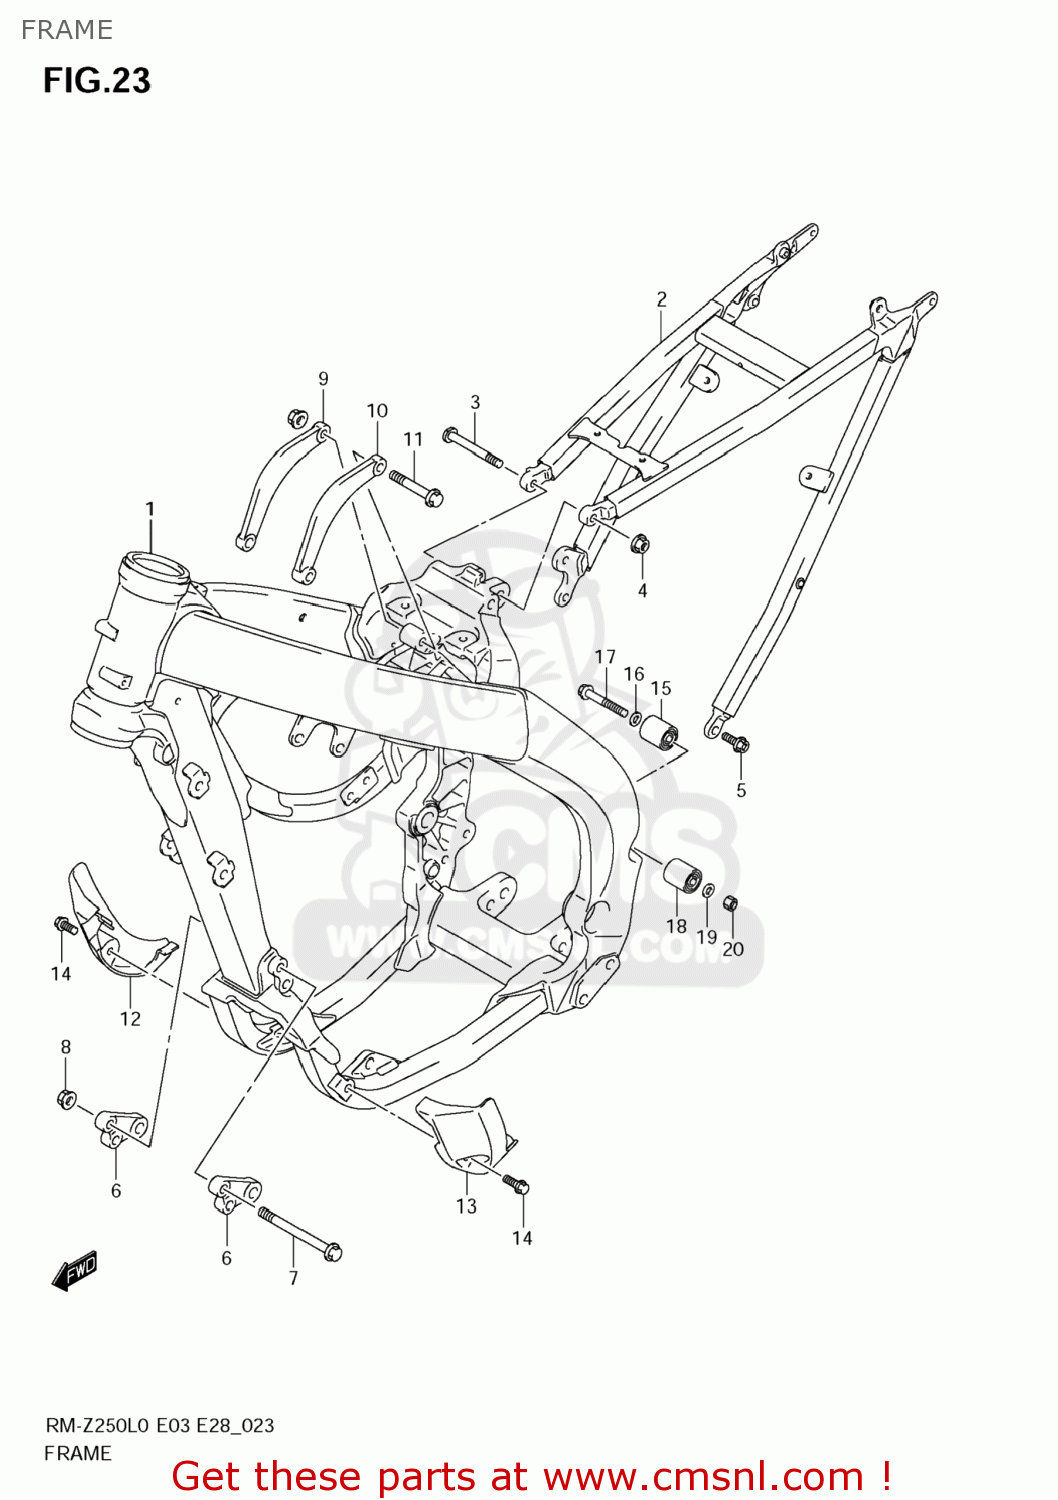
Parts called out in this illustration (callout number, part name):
1	FRAME
2	RAIL,SEAT
3	BOLT,SEAT RAIL UPR
4	NUT
5	BOLT(8X23)
6	BRACKET,ENGINE MOUNTING FR
7	BOLT(8X95)
8	NUT
9	BRACKET,ENGINE MOUNTING UPR,R
10	BRACKET,ENGINE MOUNTING UPR,L
11	BOLT(8X55)
12	PROTECTOR,FRON
13	PROTECTOR,FR,L
14	BOLT(6X16)
15	ROLLER,CHAIN
16	SHIM(8X16X1)
17	BOLT(8X45)
18	ROLLER,CHAIN
19	SHIM(8X12X1)
20	NUT
